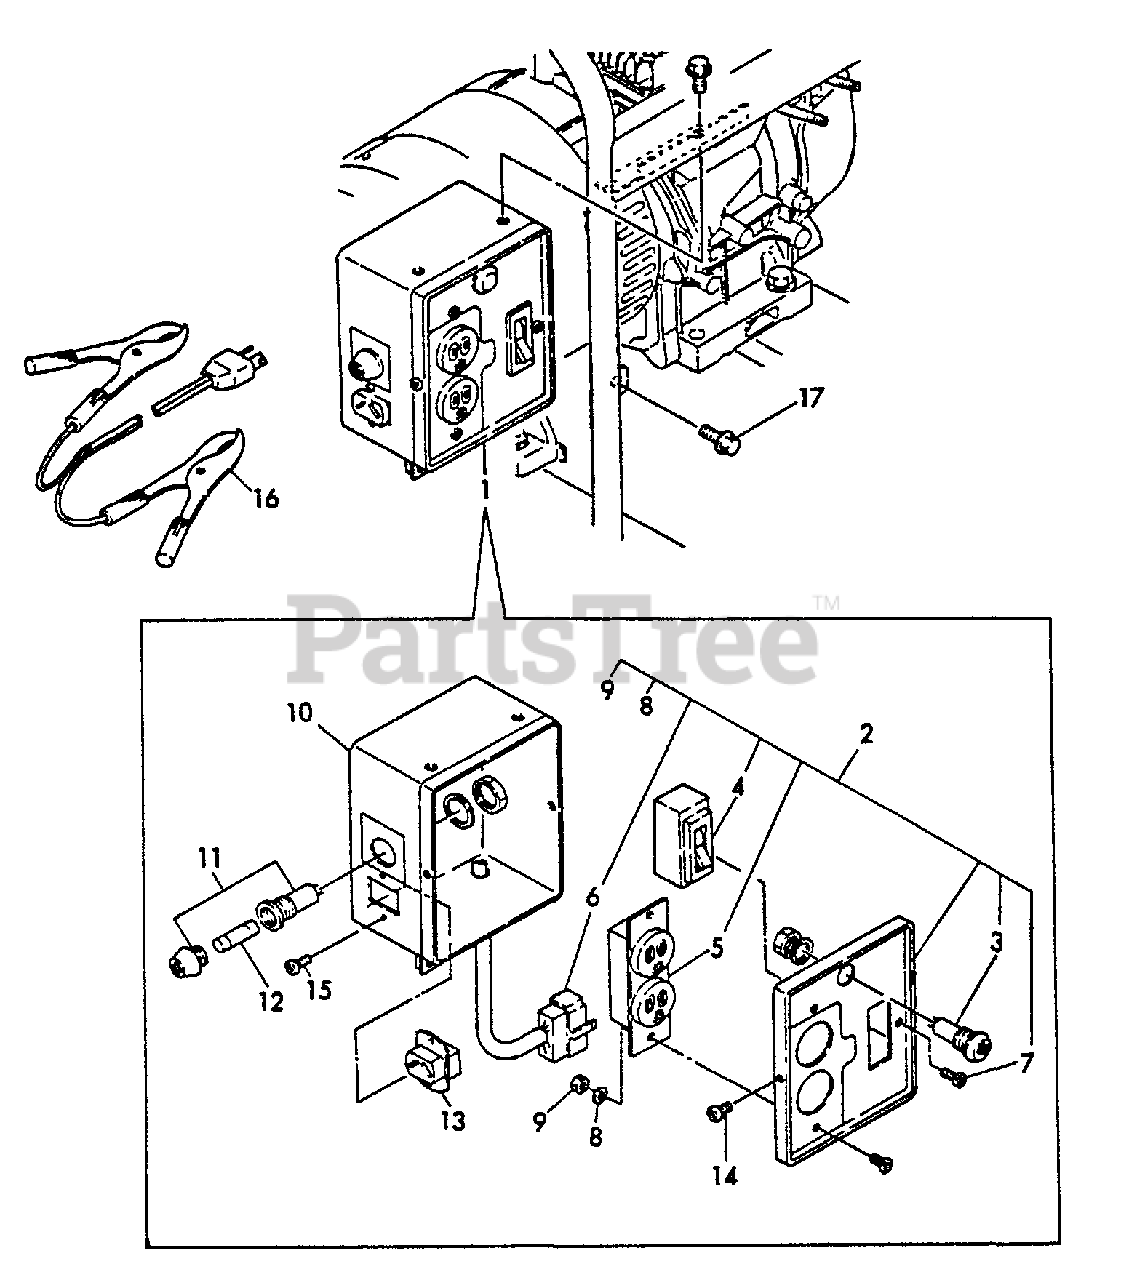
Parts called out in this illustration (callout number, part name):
1	PANEL BOX ASSY
2	PANEL ASSY
3	LAMP, PILOT - 100V
4	BREAKER - 17A
5	AC CONNECT
6	WIRE HARNESS
7	SCREW - 4X8
8	WASHER - 4
9	NUT - 4
10	BOX, PANEL
11	HOLDER, FUSE
12	FUSE - 15A
13	PLUG SOCKET 15A
14	SCREW - 4X8
15	SCREW - 3X10
17	BOLT - 6X8 -- PLATED
